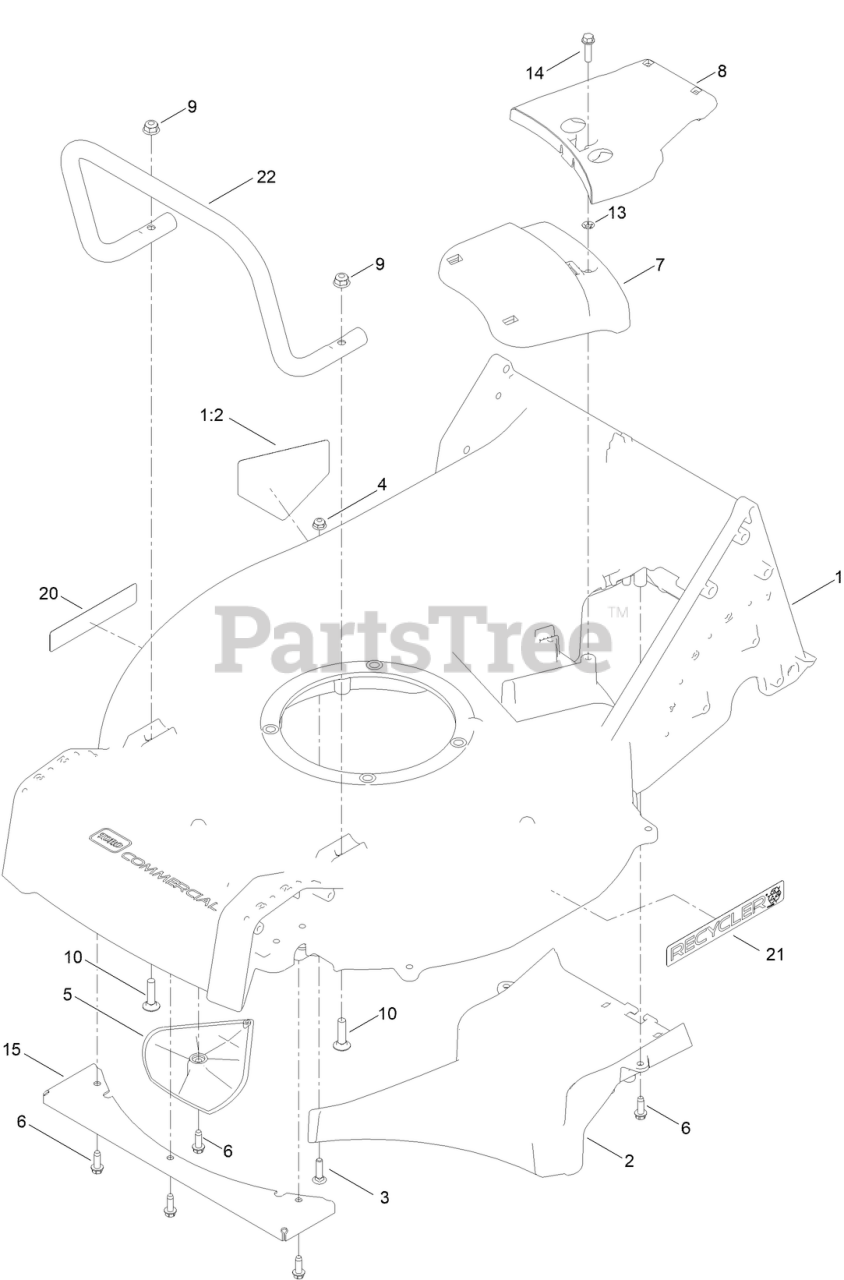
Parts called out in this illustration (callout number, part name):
1	HOUSING ASM
1:2	DECAL-DANGER
2	FLOOR-CHUTE
3	SCREW-CARR
4	NUT-HF
5	KICKER
6	SCREW-HWHTF
7	COVER-BELT, FRONT
8	COVER-BELT, REAR
9	NUT-HF, NI
10	SCREW-CARR
13	PUSHNUT-RETAINER, BOLT
14	SCREW-HWHTF
15	GUARD-TOE, FRONT
21	DECAL-RECYCLER
22	GUARD-ENGINE
